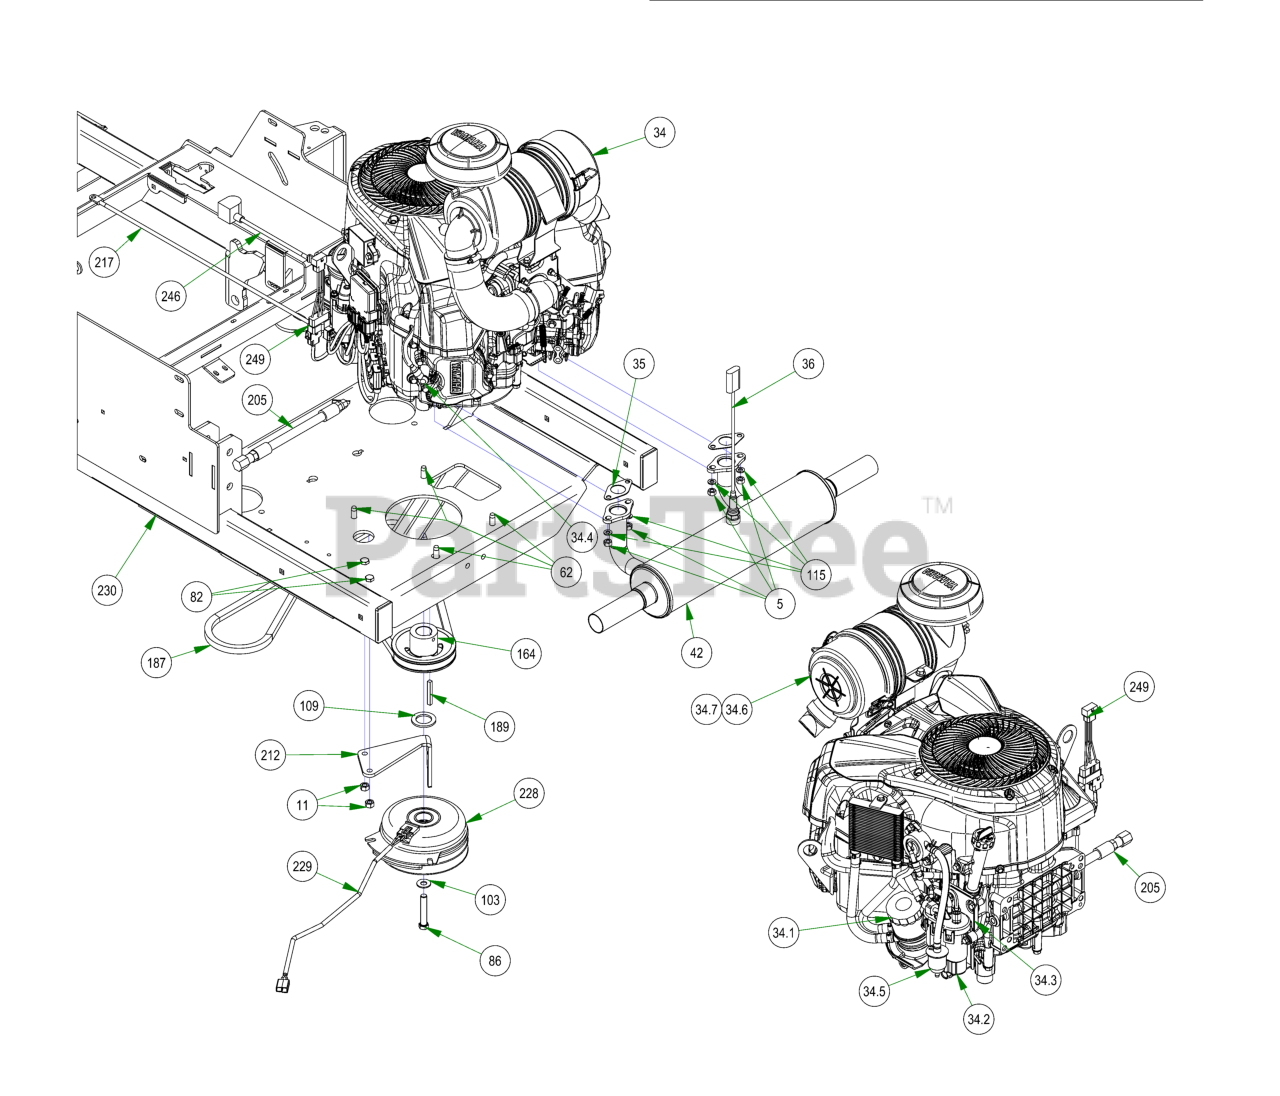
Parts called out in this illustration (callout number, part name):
5	M8-1.25 DIN 934 HEX NUT (CL.8) ZINC
11	3/8-16 HEX NUT ZINC
31	1 1/2 x 3 Frame Plug
34	Yamaha 33hp EFI Engine
34.1	Oil Filter
34.2	Yamaha Fuel Pump
34.3	Yamaha Fuel Pump Bracket
34.4	Yamaha Spark Plug
34.5	Yamaha Fuel Filter
34.6	Canister Air Filter- Outer
34.7	Canister Air Filter- Inner
35	Exhaust Gasket for yamaha
36	O2 Sensor for Yamaha
42	Muffler for 27Hp Yamaha
62	3/8-16 X 1-1/8HEX WASHER UNSLOT SERRATED
82	3/8-16 X 1-1/4 HEX CAP SCREW (GR.5) ZINC
86	7/16-20 X 2-1/2 HEX Bolt GR 8 W/ Patch
103	3/8 FLAT WASHER USS (1" OD) ZINC
109	1.140 ID X 1.750 OD X .132 THICK FLAT WASHER PLAIN
115	5/16 SPLIT LOCKWASHER ZINC
164	4 3/4 Motor Pulley
187	2019 Rogue Pump Belt 68"
189	1/4 X 2 SQ MACHINERY KEY 1018 STL PLAIN
205	Oil drain Hose for Yamaha
212	PTO Engager Holder
217	24" Red Battery Cable
228	Clutch Assembly
229	Clutch Pigtail
230	2021 Rogue Suspension Frame Painted
246	Starter Cable
249	2019 Harness Adaptor - Vanguard 37 EFI Vert/Horiz
